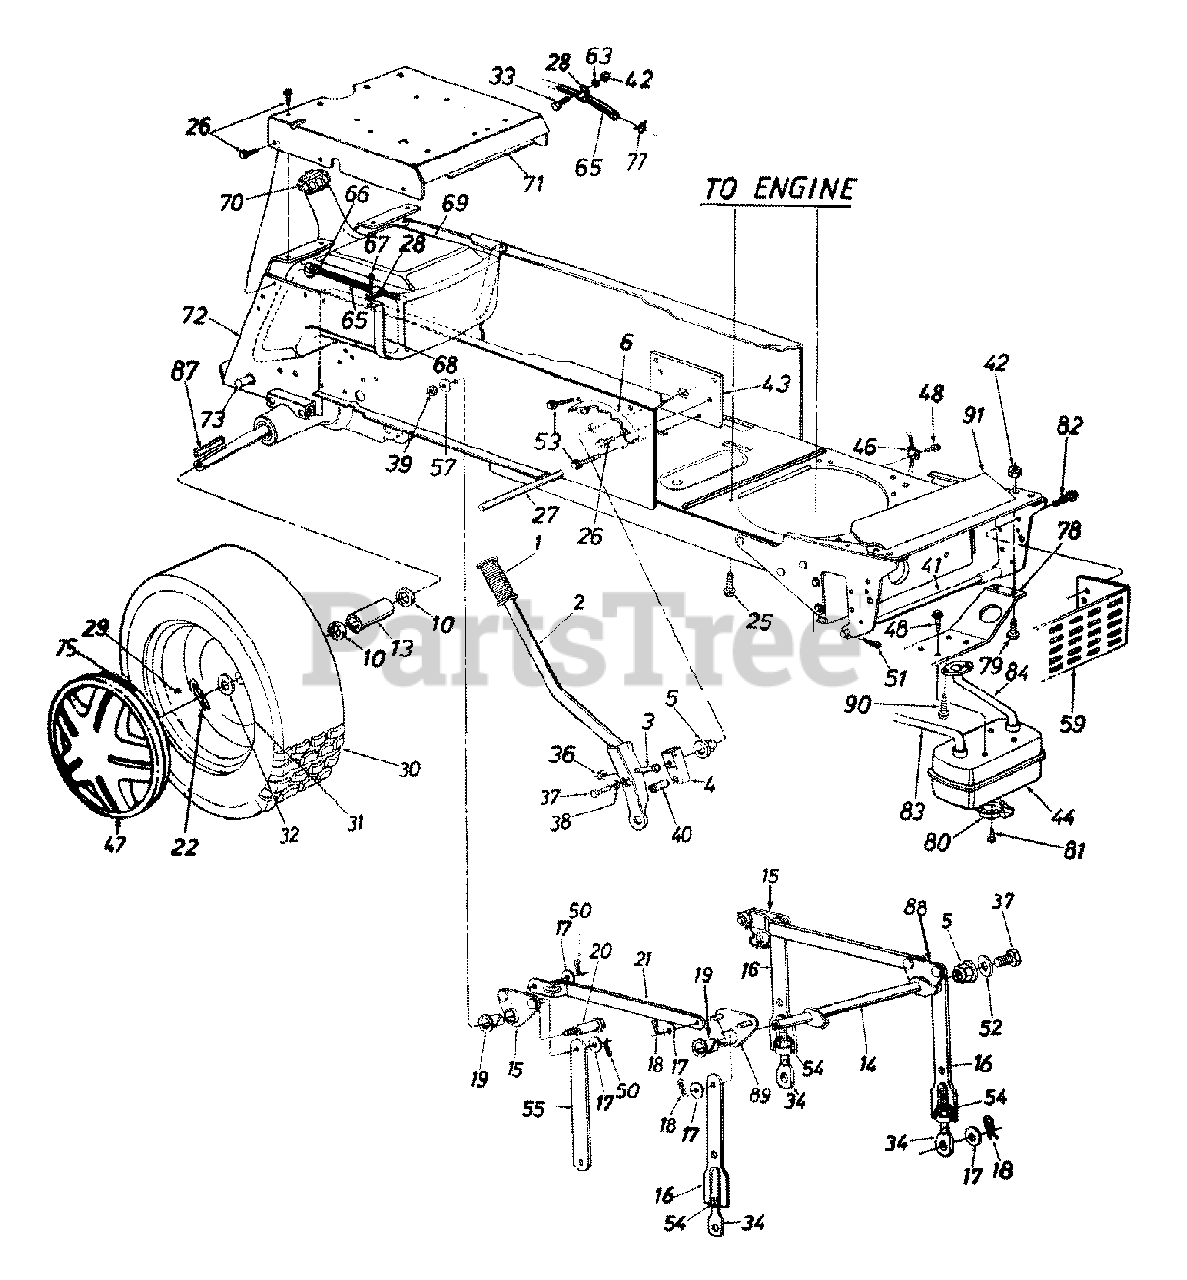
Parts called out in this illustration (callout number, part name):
1	Grip
2	Lift Handle Ass'y.
3	Hex Bolt 5/16-18 x 1.5" Lg.
4	Lift Shaft Drive
5	Plastic Hex Brg. 5/8" I.D.
10	Fl-Wash. 1.03" I.D. x 1.62" O.D.
13	Spacer 1" I.D. x 1.25" O.D.
14	Lift Shaft Ass'y.
15	Lift Pivot Brkt. Ass'y.
17	Fl-Wash. 1/2" I.D. x 1.00" O.D. x .090"
18	Hairpin Cotter
19	Flanged Brg. 5/8" I.D.
20	Shld. Bolt 5/8" Dia. x .96" Lg. 3/8-16
25	Hex Wash. Hd. Scr. 3/8-16 x 1.25" Lg.
26	Hex Thd. Rolling Scr. 5/16-18 x .75" Lg.
27	Running Board Rod
29	Air Valve
33	Hex Bolt 1/4-20 x .62" Lg.
34	Eye Bolt Adj. Link 1/2-13 Thd.
36	Hex Cent. L-Nut 5/16-18 Thd.
37	Hex Bolt 5/16-24 x .75" Lg. (Gr. 5)
39	Hex Top L-Nut 3/8-16 Thd.
40	Compression Spring
41	Deck Connecting Rod
42	Hex Sems Nut 1/4-20 Thd.
46	Mounting Clamp
47	Hub Cap
48	Hex Wash. Hd. TT-Tap Scr. 1/4-20 x .5" Lg.
50	Cotter Pin .09 Dia. x 1.0" Lg.
51	Int. Cotter Pin
52	Flat Wash. .34" I.D. x 1.12" O.D. x .125"
53	Hex Wash. Hd. AB-Tap Scr. 5/16-18 x .5" Lg.
54	Hex Nut 1/2-13 Thd.
57	Bell-Wash. .4" I.D. x 1.13" O.D.
65	Fuel Line 46" Lg.
67	Hex AB-Tap Scr. 1/4 x .62" Lg.
68	Fuel Tank Strap
71	Seat Plate
75	Spring Clip
78	Muffler Mounting Brkt.
79	Hex Bolt 1/4-20 x .62" Lg.
80	Muffler Deflector
81	Hex Wash. Hd. F-Tap Scr. #8 x .32" Lg.
82	Hex Wash. Hd. TT-Tap Scr. 5/16"-18 x .62" Lg.
83	Exhaust Tube - R.H.
84	Exhaust Tube - L.H.
87	Sq. Key 1/4" x 3" Lg.
88	Lift Pivot Brkt. - L.H.
89	Lift Pivot Brkt. - R.H.
90	Socket Scr. M8 x 1.25" x 20MM Lg.
91	Heat Shield
